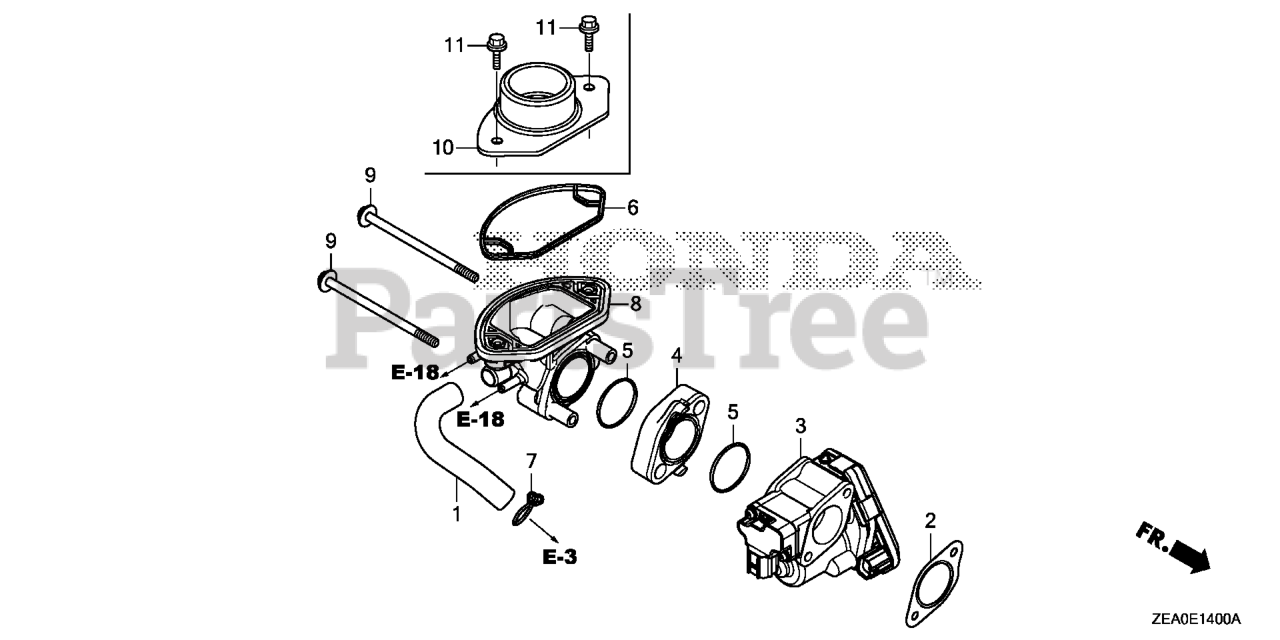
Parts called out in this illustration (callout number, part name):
1	TUBE, BREATHER
2	GASKET, THROTTLE BODY
3	BODY ASSY., THROTTLE
4	SPACER, THROTTLE BODY
5	GASKET, AIR CLEANER
6	SEAL, AIR CLEANER HOUSING
7	CLIP, BREATHER TUBE
8	ELBOW, AIR CLEANER
9	BOLT, FLANGE (6X106)
